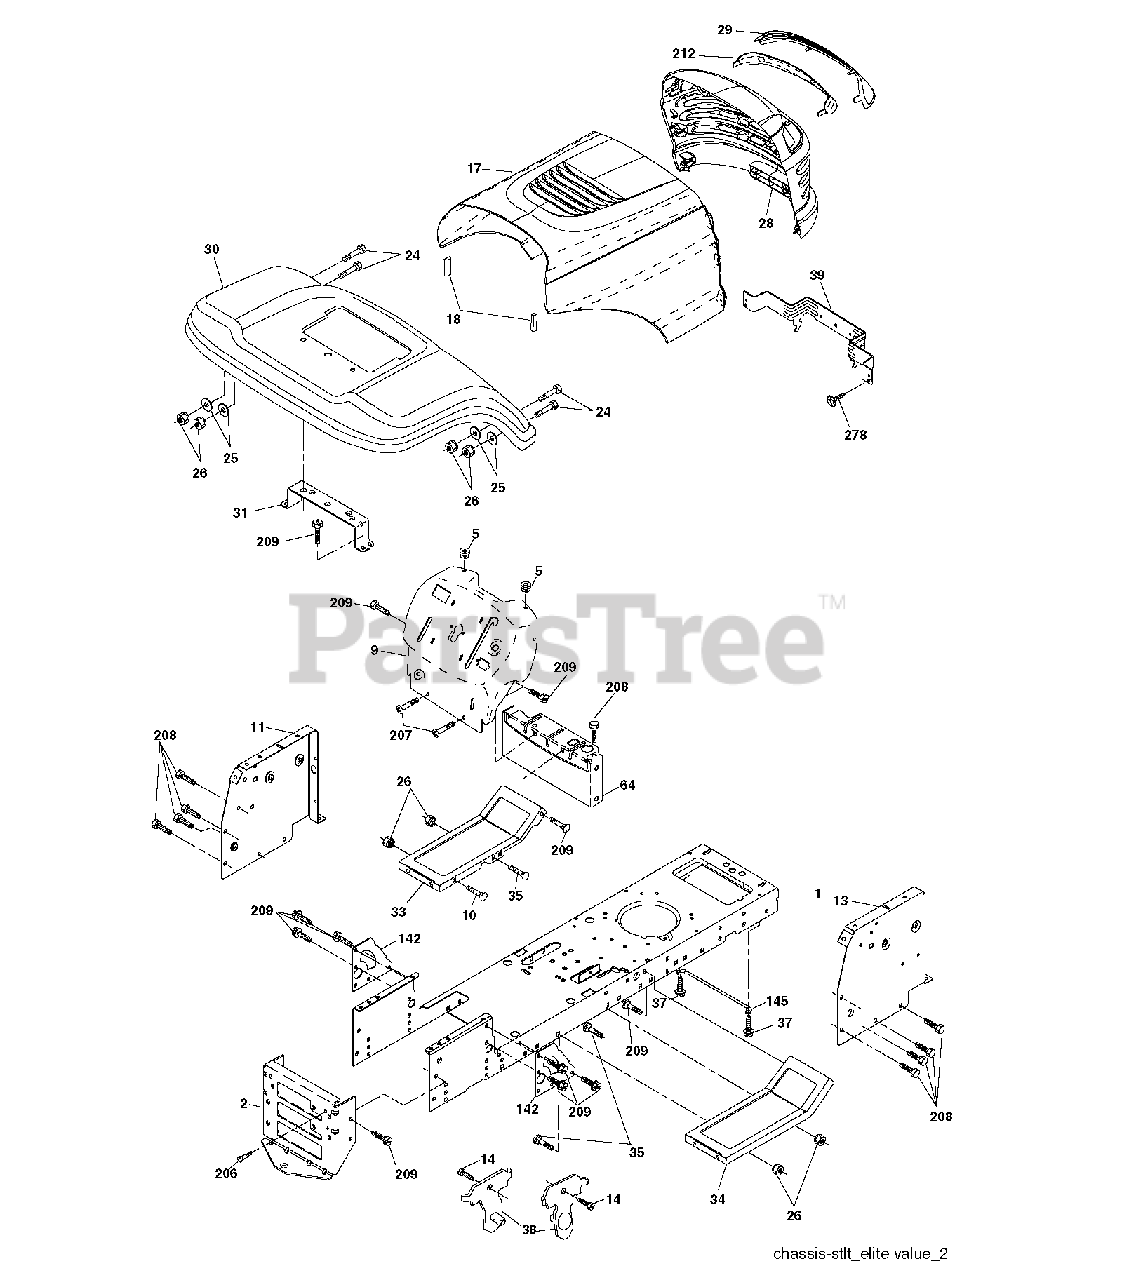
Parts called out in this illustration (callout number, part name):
1	CHASSIS STAMPING
2	DRAWBAR, 12GA
5	BUMPER.RUBBER.HOOD
10	BOLT D
11	PANEL.DASH.LH.LTX
14	SCREW LT
18	BUMPER.HOOD.LARGE.1.75"
24	BOLT
25	WASHER
26	NUT
31	BRACKET FENDER
35	BOLT
37	SCREW LT
38	BRACKET.ASM.PIVOT.MOWER.REAR
39	BRACKET PIVOT
64	DASH LOWER
142	PLATE REINFORCEMENT
145	ROD.PIVOT.HOOD
206	SHOULDER BOLT 5/16-18TT
207	SCREW 5/16-18X1/2"
208	SCREW 3/8-16X1/2
209	SCREW, 3/8-16X3/4
278	SCREW
